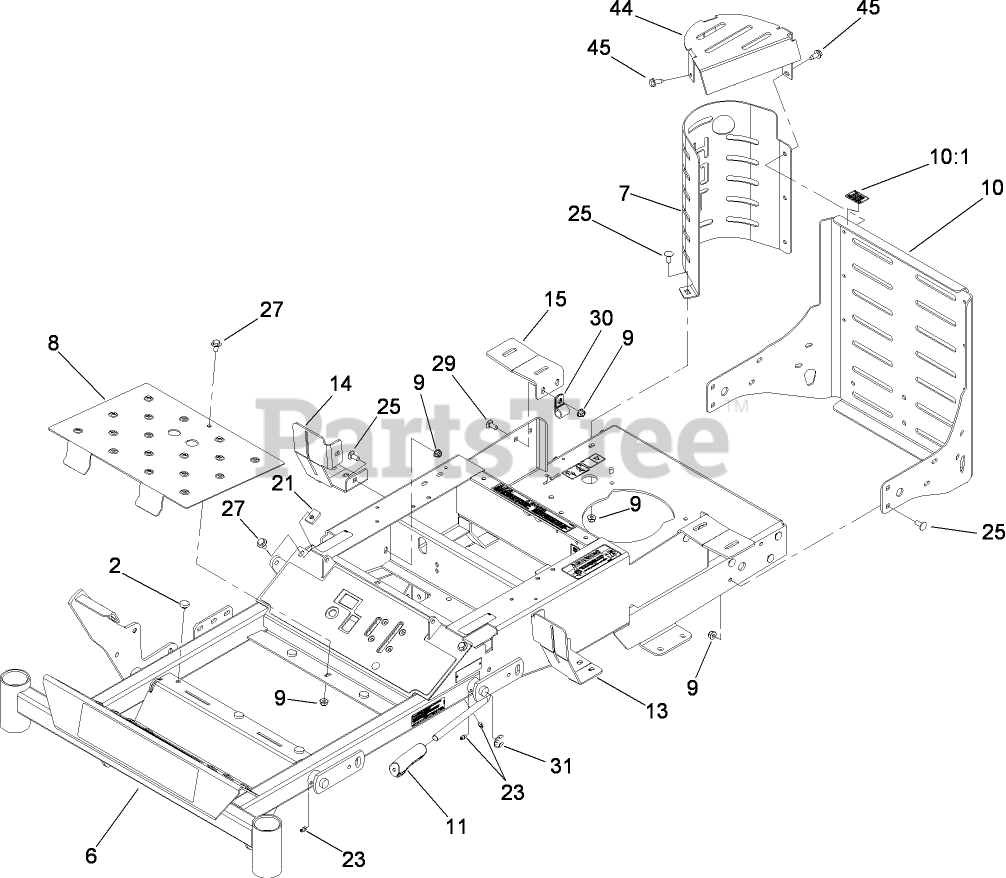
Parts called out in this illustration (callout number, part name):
2	BUMPER
6	FRAME ASM
7	GUARD-MUFFLER
8	PLATE-FLOOR
9	NUT-HF, NI
10	REAR GUARD ASM
10:1	DECAL-SURFACE, HOT
11	GRIP-LEVER, BRAKE
13	MOUNT-TANK, FUEL (LH)
14	MOUNT-TANK, FUEL (RH)
15	BRACKET-FUEL TANK, REAR
21	STOP-MOTION
23	FITTING-GREASE
25	SCREW-CARR
27	SCREW-HHF
29	SCREW-CARR
30	CLIP-LOOM
31	E-RING
44	SHIELD-HEAT
45	SCREW-HWHTF
